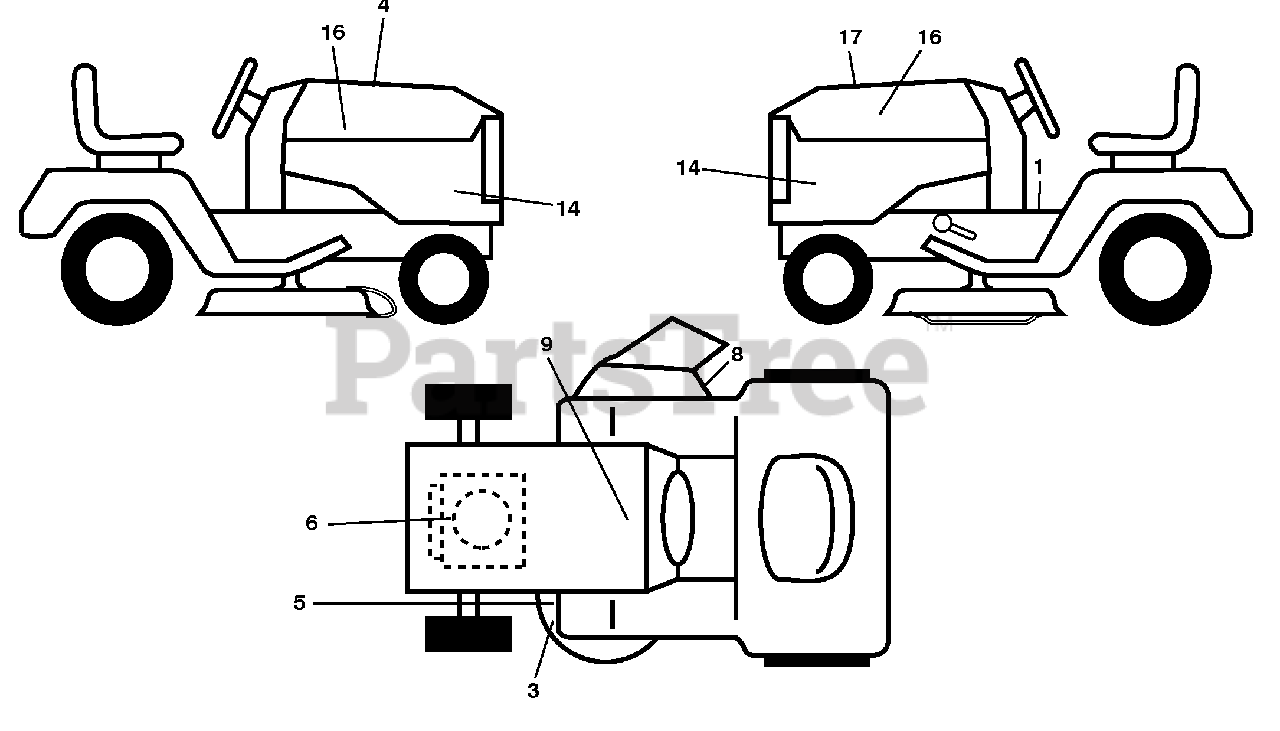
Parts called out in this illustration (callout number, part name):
1	Decal, Fender Warning
3	Decal, Warning
4	Decal, Hood Cust Resp
5	Decal, Caution
6	Decal, Eng. HP
8	Decal, Mower Sch.
9	Decal, Battery Dnge/Poi
14	Decal, Panel Side
16	Decal, Hood Logo
17	Decal, Replacement
